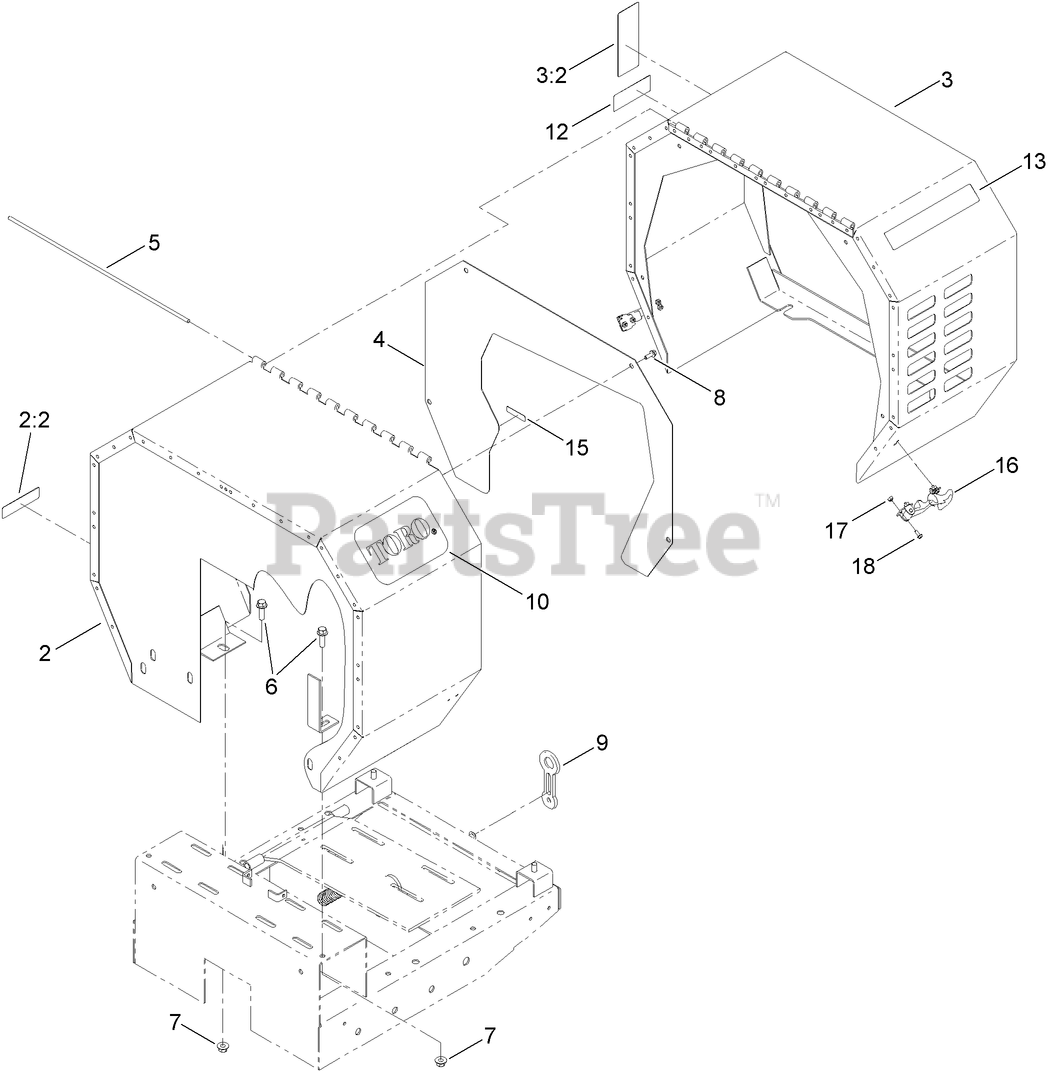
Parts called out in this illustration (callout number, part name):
2	STATIONARY COWL ASM
2:2	DECAL-ARRESTER, SPARK
3	MOVABLE COWL ASM
3:2	DECAL-WARNING
6	SCREW-HHF
7	NUT-FLANGE
8	SCREW-HHF
9	LATCH-RUBBER
10	DECAL
15	DECAL-GREASE
16	LATCH-FLEX, DRAW
17	NUT-LOCK, NI
18	SCREW-HWH
